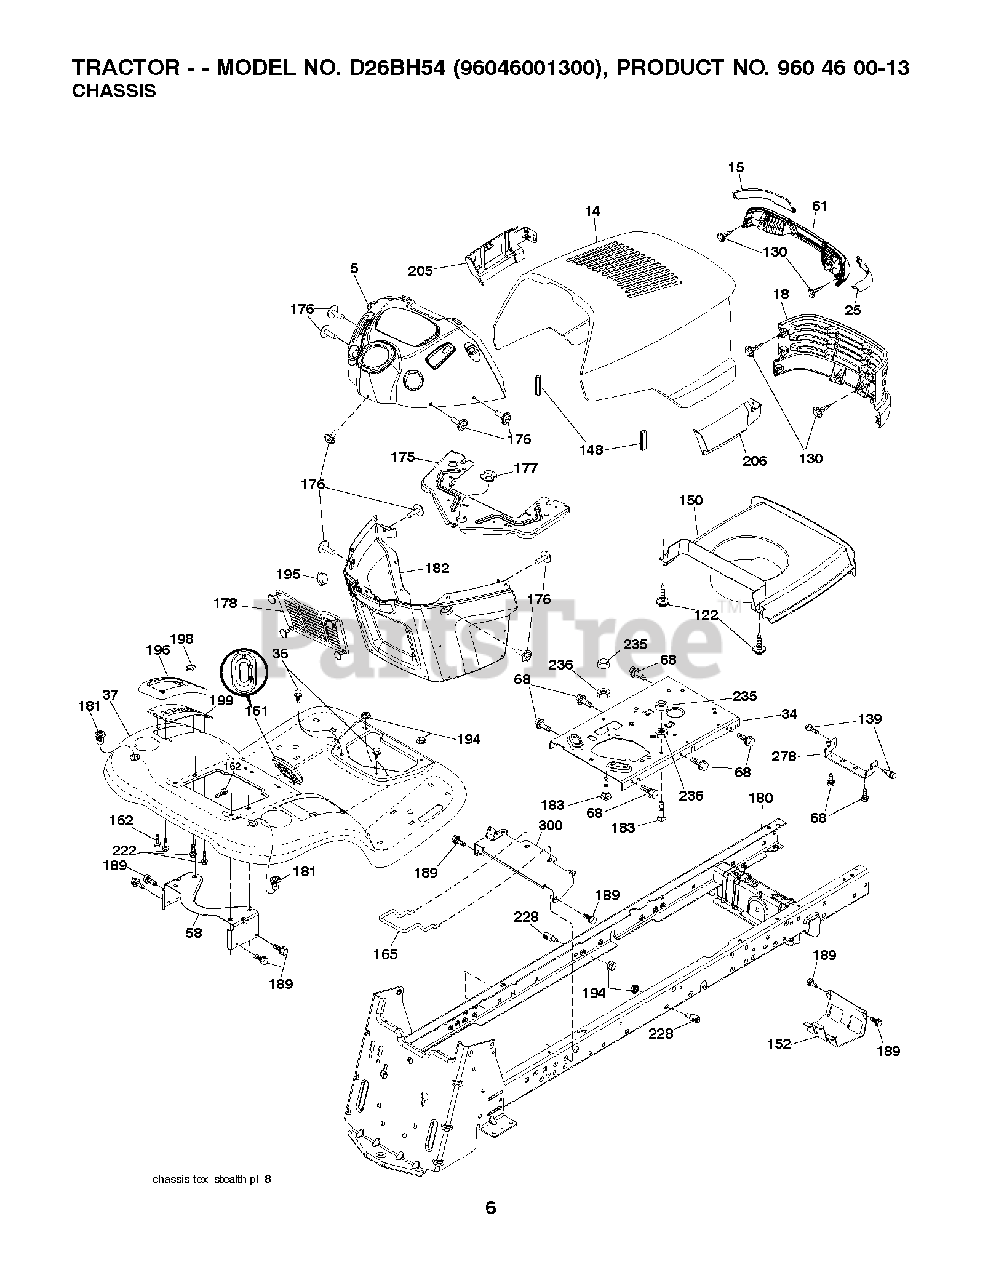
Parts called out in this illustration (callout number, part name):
5	DASH.STEALTH.EL.LIFT.RND.BLACK
14	HOOD.ASM.DIXON.STEATH.SRS.BLUE
15	LENS LH
18	GRILLE.STEALTH.GT.BLACK
25	LENS RH
34	PLATE.ENGINE.WELDED.CHASSIS
36	SCREW 5/16"
37	FENDER.BLUE.TXGT.ERGO.SD.FILL
58	BRKT.SUPPORT.FNDR/TANK
61	LIGHTBOX.ASM.STEALTH.DL.DIXON
68	SCREW LT
122	SCREW.WSHD.HEX10-32X5/8
130	SCREW.#10 X 0.750.BOS (2 2)
139	BOLT, SHOULDER 5/16-18
148	EXTRUSION BUMPER
150	DUCT.HEAT.HOOD.STEALTH.GT
152	SHIELD.BROWNING.W/TEX
161	CONSOLE.FUEL.WINDOW.STGT.BLACK
162	SCREW.HI-LO.CONSOLE
165	SUPPORT.TANK.REAR.B/TE
175	CROSSMEMBER.
176	SCREW.#10-24X5/8.RN.QU
177	BUSHING,STEERING
178	CARGO.ASM.NET.DASH.LOWER
180	CHASSIS.GT.SLOPED.DRAWBAR.
181	FEND/FTRST.PCH.CPH.NFW
182	DASH.LOWER.
183	BOLT.5/16-18X1-1/4 FULL THD
189	SCREW
194	NUT LOCK HEX FLANGE 5/16-18
195	PLUG.HOLE.DASH.
196	CONSOLE.ASM.DECK.
198	INDICATOR DECK LIFT
199	PLATE.DECK.LIFT.ELECTRIC
205	SKIRT.GRILLE.STEALTH.RH
206	SKIRT.GRILLE.STEALTH.LH
222	SCREW.1/4-20X5/8
228	STUD.FASTNER.W/ANTI-ROTATE
235	SPACER FENDER
236	NUT.CENTERLOCK.5/16-
278	BRKT.HOOD/MUFF.STEALTH
300	BRACKET.ASM.LIFT.ELECTRIC
